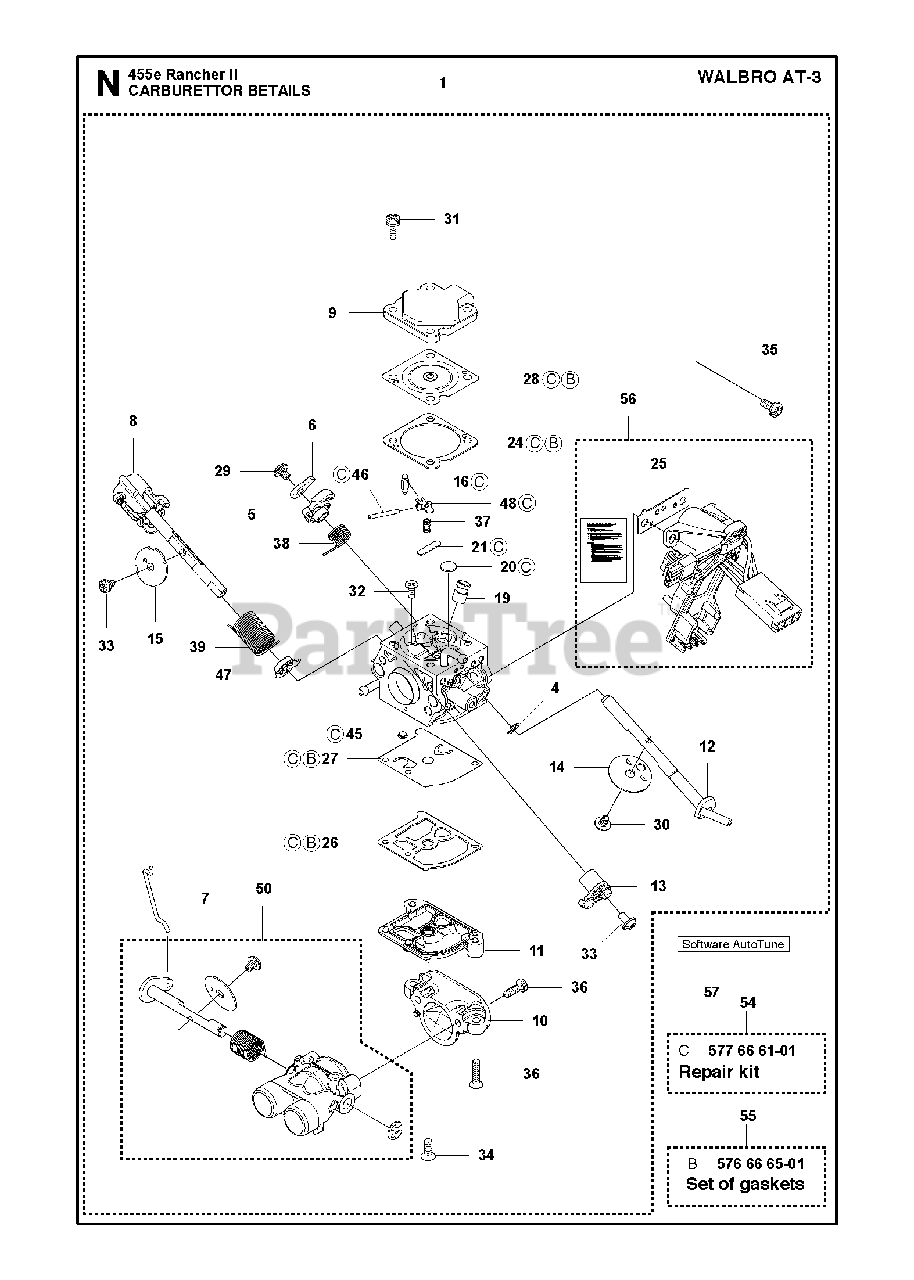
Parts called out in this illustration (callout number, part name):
1	CARBURETOR
4	RETAINER
5	LEVER
6	LEVER
7	LINK
8	THROTTLE LEVER
9	COVER
10	INLET
11	COVER
12	SHAFT ASSY
13	THROTTLE SHAFT
14	VALVE
15	THROTTLE VALVE
16	INLET NEEDLE
19	MAIN NOZZLE
20	PLUG WELCH
21	PLUG
24	GASKET
25	GASKET
26	GASKET
27	DIAPHRAGM
28	DIAPHRAGM ASSY
29	SCREW
30	SCREW
31	SCREW
32	SCREW
33	SCREW
34	SCREW
35	Screw
36	SCREW
37	SPRING
38	SPRING
39	SPRING
45	FUEL INLET SCREEN
46	FULCRUM PIN
47	BUSHING
48	LEVER
50	THROTTLE VALVE ASSY
54	REPAIR KIT
55	GASKET KIT
56	SPARE PARTS KIT
57	Husqvarna TBD
